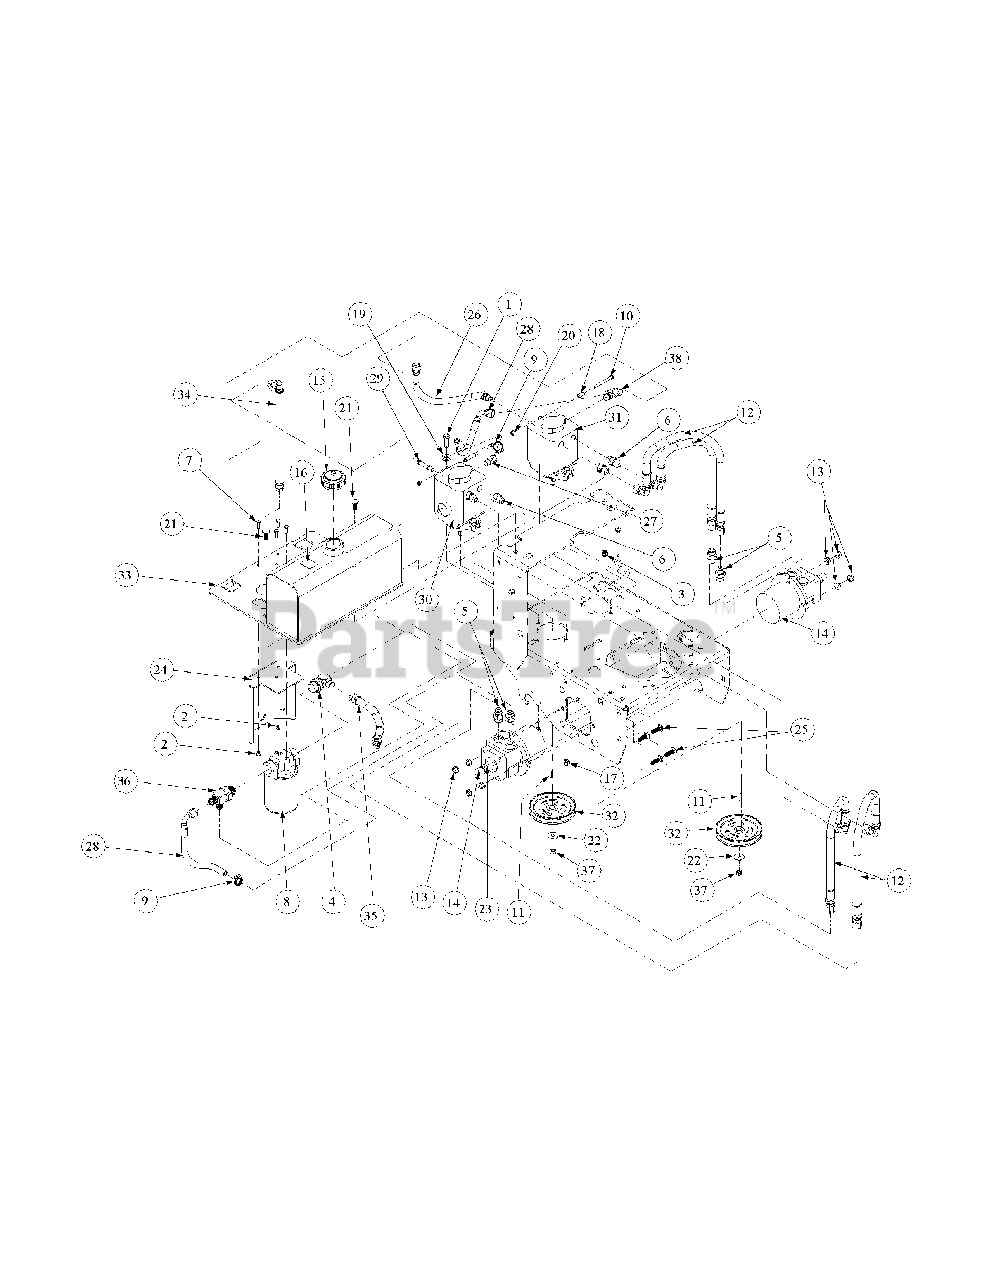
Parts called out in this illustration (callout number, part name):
1	Cap Screw, Standard, 3/8-16 x 1-1/4
2	Lock Nut Nylon Insert, 1/4-20
3	Lock Nut, 3/8-16
4	Elbow 90ø 1/2 x 3/4
5	Fitting, Aeroquip
6	Fitting, Aeroquip
7	Cap Screw, 1/4-20 x 3/4
8	Filter Head 3/4
9	Worm Gear Clamp, 5/16-7/8
10	Cap Screw, Socket Head, 1/4-20 x 1-1/2 Zinc
11	Key, 3/16" x 7/8"
12	Reverse Pressure Hydraulic Hose Assembly
13	Flange Lock Hex Nut, 3/8-16
14	Hydraulic Motor, Wheel
15	Cap, Hydraulic Oil Tank
16	Oil Label, 20W-50
17	Lock Nut, 3/8-16
18	Spacer, Pump Release
19	Washer, Idler
20	Hex Lock Nut, 1/4-20
21	Carriage Bolt, 3/8-16 x 1.0
22	Bell Washer, .396 x 1.140 x .095
23	Woodruff Key, 3/16 x 3/4
24	Filter Guard Weldment
25	Carriage Bolt, 3/8-16 x 1.25
26	Left Pump Inlet Hose
27	Push On Fitting 45
28	Right Pump Inlet Hose
29	Push On Straight Fitting
30	Right Hand, Hydro Pump, BDP 10A 308
31	Left Hand, Hydro Pump, BDP 10A 413
32	Hydro Pump Pulley, 5.00 Dia
33	Fuel Tank Mounting Bracket and Integrated Hydraulic Tank
34	Left Hand, 14.25 Return Hose Assembly
35	9.5" Supply Hose Assembly
36	Tee Fitting, 3/4 x 1/2 x 1/2
37	Hex Nut, 3/8-24
38	Tee Fitting
